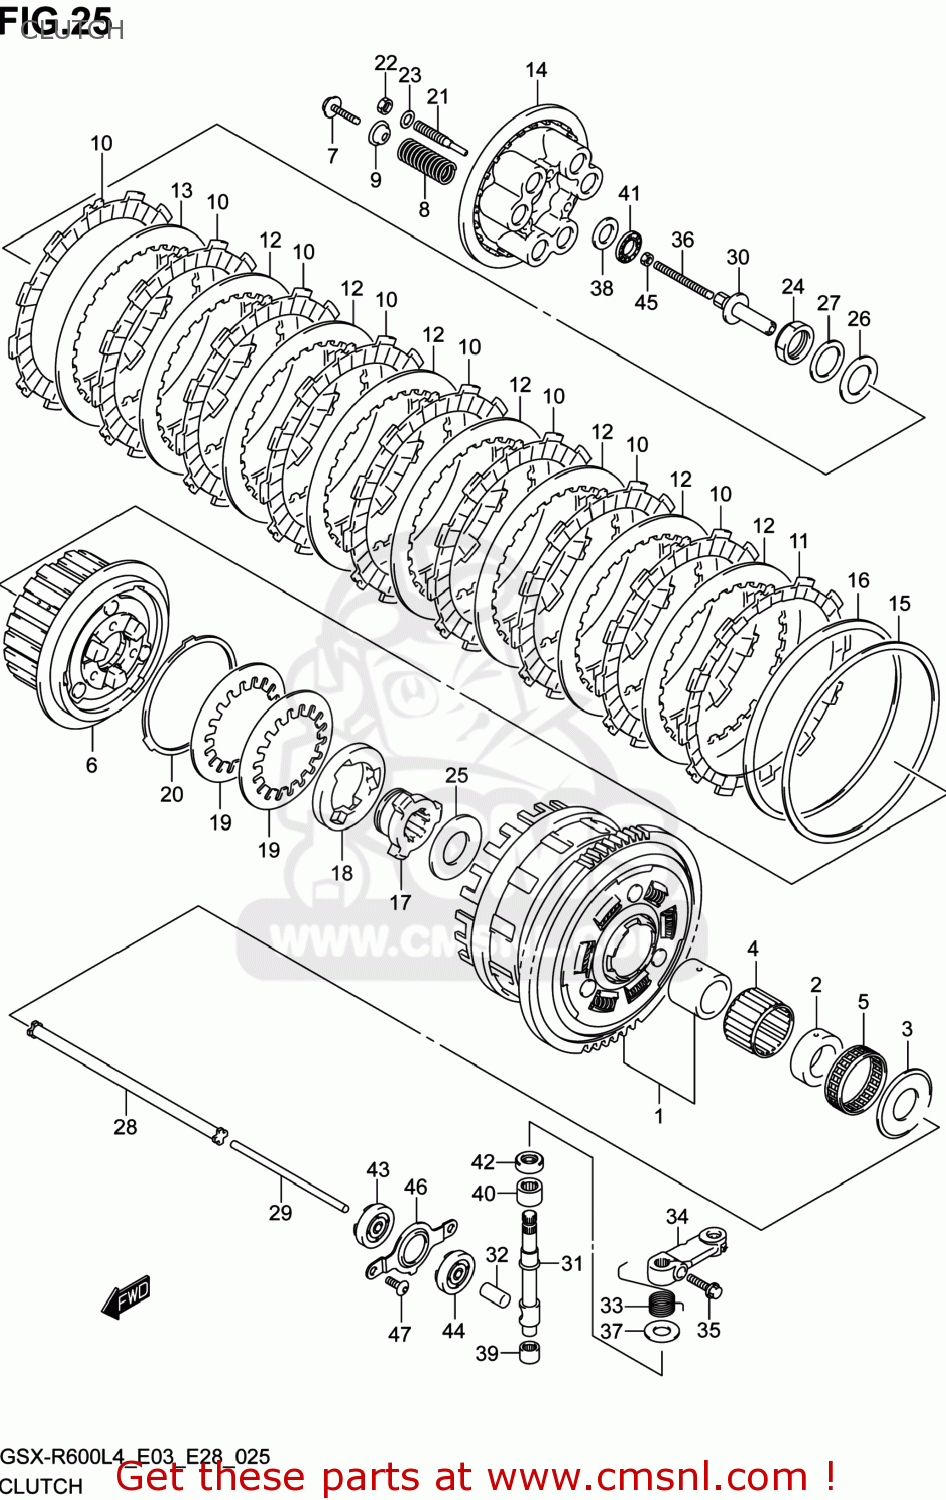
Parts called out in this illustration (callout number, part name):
1	GEAR SET,PRI DRIVEN
2	SPACER,OIL PUMP DRIVE SPROCKET
3	WASHER(25X54X2.4)
4	BEARING(35X40X26.8)
5	BEARING(35X40X12)
6	HUB,CLUTCH SLEEVE
7	BOLT,CLUTCH SPRING
8	SPRING,CLUTCH
9	WASHER
10	PLATE,CLUTCH DRIVE NO.1 (NAS)
11	PLATE,CLUTCH DRIVE NO.3 (NAS)
12	PLATE,CLUTCH DRIVEN (NAS)
13	PLATE,CLUTCH DRIVEN (NAS)
14	DISC,CLUTCH PRESSURE
15	SEAT,WAVE WASHER
16	WASHER,CLUTCH PLATE WAVE
17	CAM,CLUTCH DRIVE
18	CAM,CLUTCH DRIVEN
19	WASHER,CAM REACTION WAVE
20	WASHER,CAM REACTION SEAT
21	LIFTER,CLUTCH PRESSURE DISC
22	NUT,CL PRESS DISC LIFTER LOCK
23	SHIM(8.8X14X1)
24	NUT
25	WASHER(25X50X2.5)
26	WASHER
27	WASHER(25X41X2.5)
28	ROD,CLUTCH PUSH,R
29	ROD,CLUTCH PUSH,L
30	PIECE,CLUTCH PUSH
31	CAMSHAFT,CLUTCH RELEASE
32	CAP,CLUTCH PUSH ROD
33	SPRING,CLUTCH RELEASE RETURN
34	ARM,CLUTCH RELEASE
35	BOLT(6X20)
36	SCREW(6X73)
37	WASHER(10.5X24X1)
38	WASHER(15.5X28X1)
39	BEARING(10X14X10)
40	BEARING(12X18X12)
41	BEARING(15X28X2)
42	SEAL,OIL(10X20X6)
43	SEAL,OIL(6X34X10.5)
44	SEAL,OIL(10X17X5)
45	NUT
46	RETAINER,CL PUSH ROD OIL SEAL
47	SCREW(6X13)
